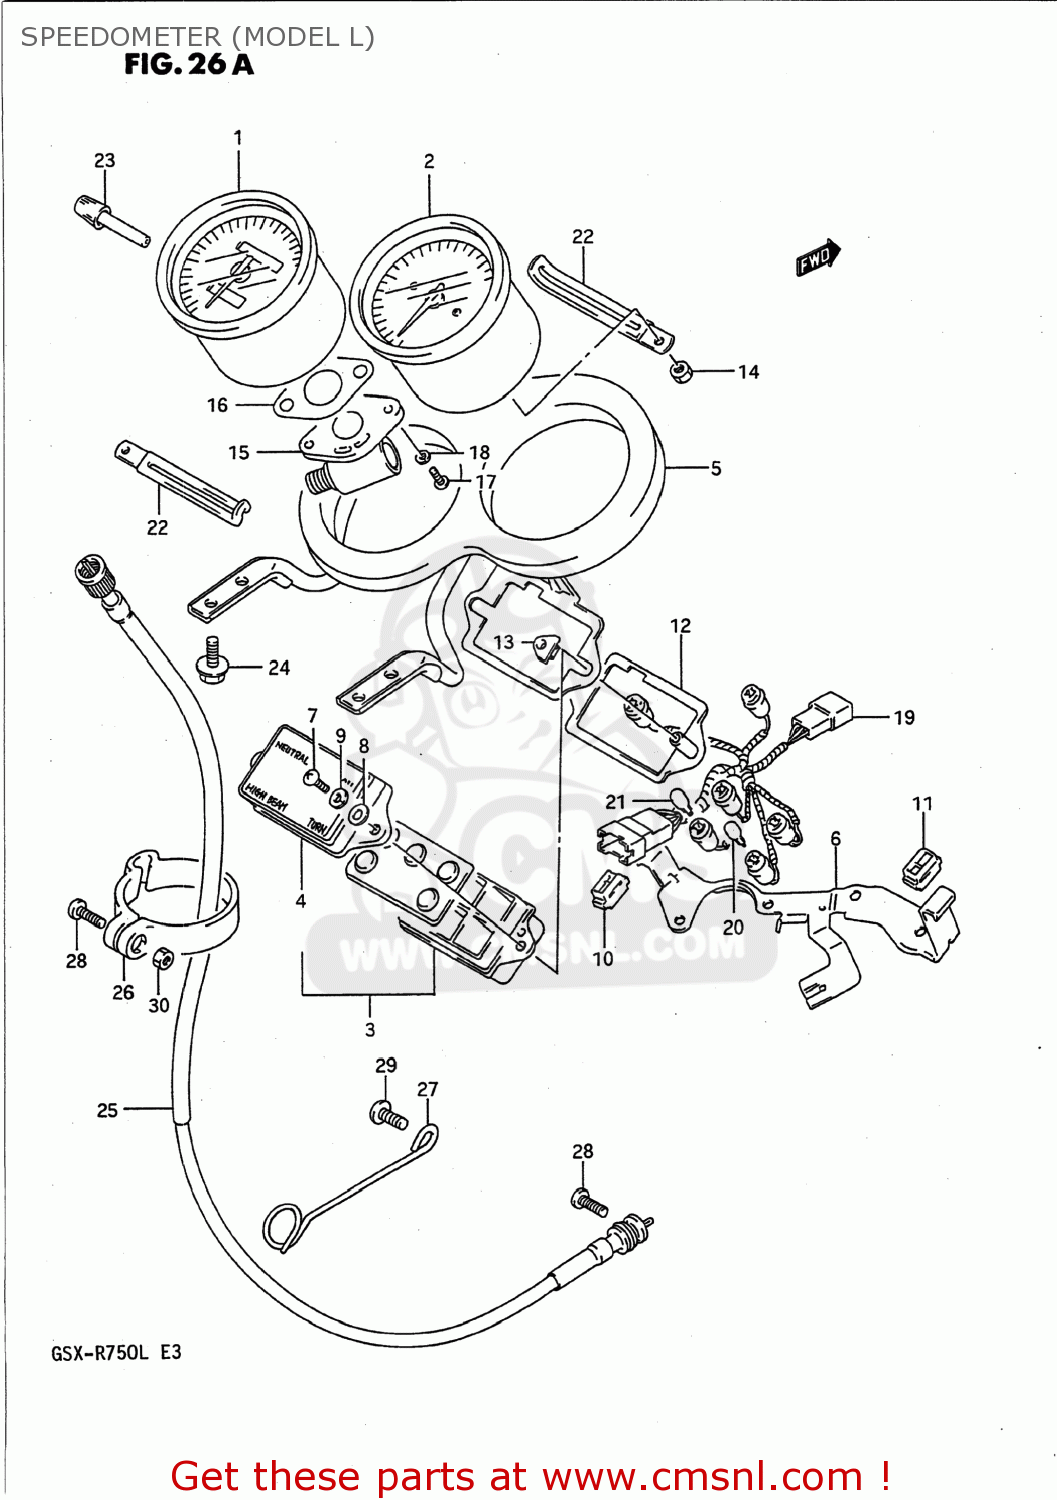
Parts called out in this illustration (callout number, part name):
1	SPEEDOMETER ASSEMBLY
2	TACHOMETER
3	BOX ASSEMBLY,PILOT LAMP
4	LENS,BOX
5	PLATE,SETTING
6	BRACKET
7	SCREW
8	WASHER
9	WASHER,LOCK 4M
10	DAMPER,LEFT
11	CUSHION
12	PLATE,SETTING
13	DAMPER
14	NUT
15	GEAR BOX
16	GASKET,METER GEAR BOX (NAS)
17	SCREW
18	LOCK WASHER
19	SOCKET,METER
20	BULB(12V3W,T6.5)
21	BULB(12V1.7W,T6.5)
22	CLAMP
23	KNOB,TRIP
24	BOLT 6X12
25	CABLE ASSEMBLY,SPEEDOMETER
26	CLAMP,SPEEDOMETER CABLE
27	GUIDE,SPEEDOMETER CABLE NO.3
28	SCREW
29	SCREW
30	NUT
